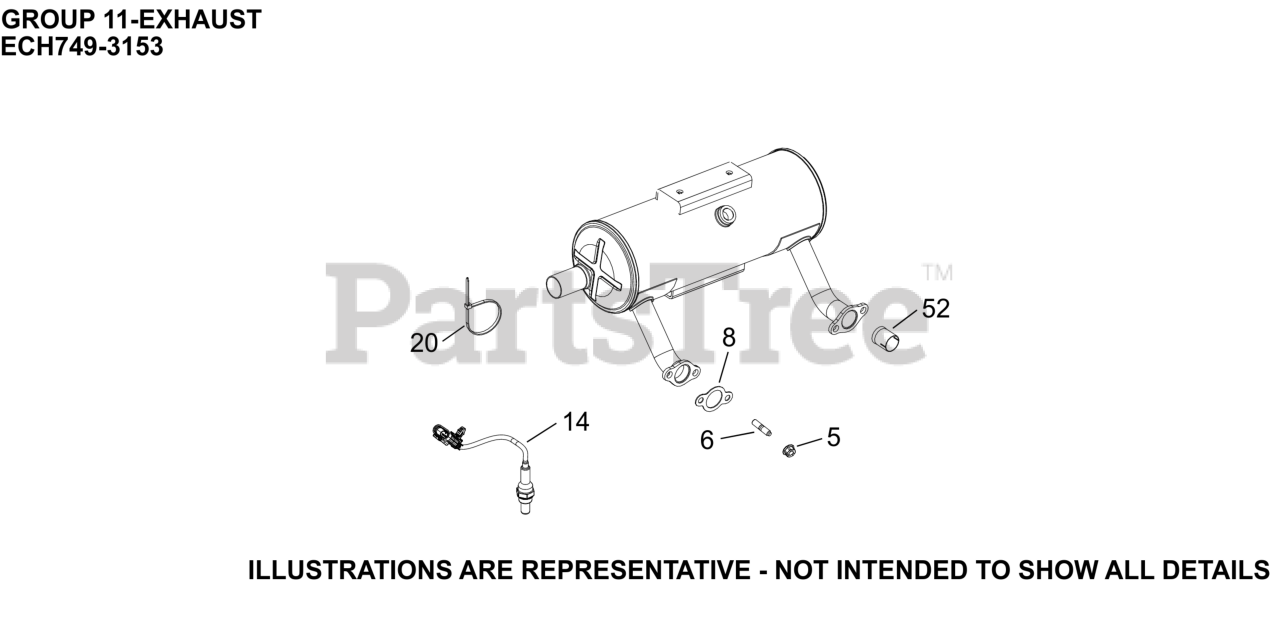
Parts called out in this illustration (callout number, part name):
5	NUT, HEX FLANGE LOCK (M8)
6	STUD, METRIC EXHAUST
8	GASKET, EXHAUST MANIFOLD
14	SENSOR, OXYGEN (M18 x 1.5 THREADS)
52	LINER, EXHAUST PORT
